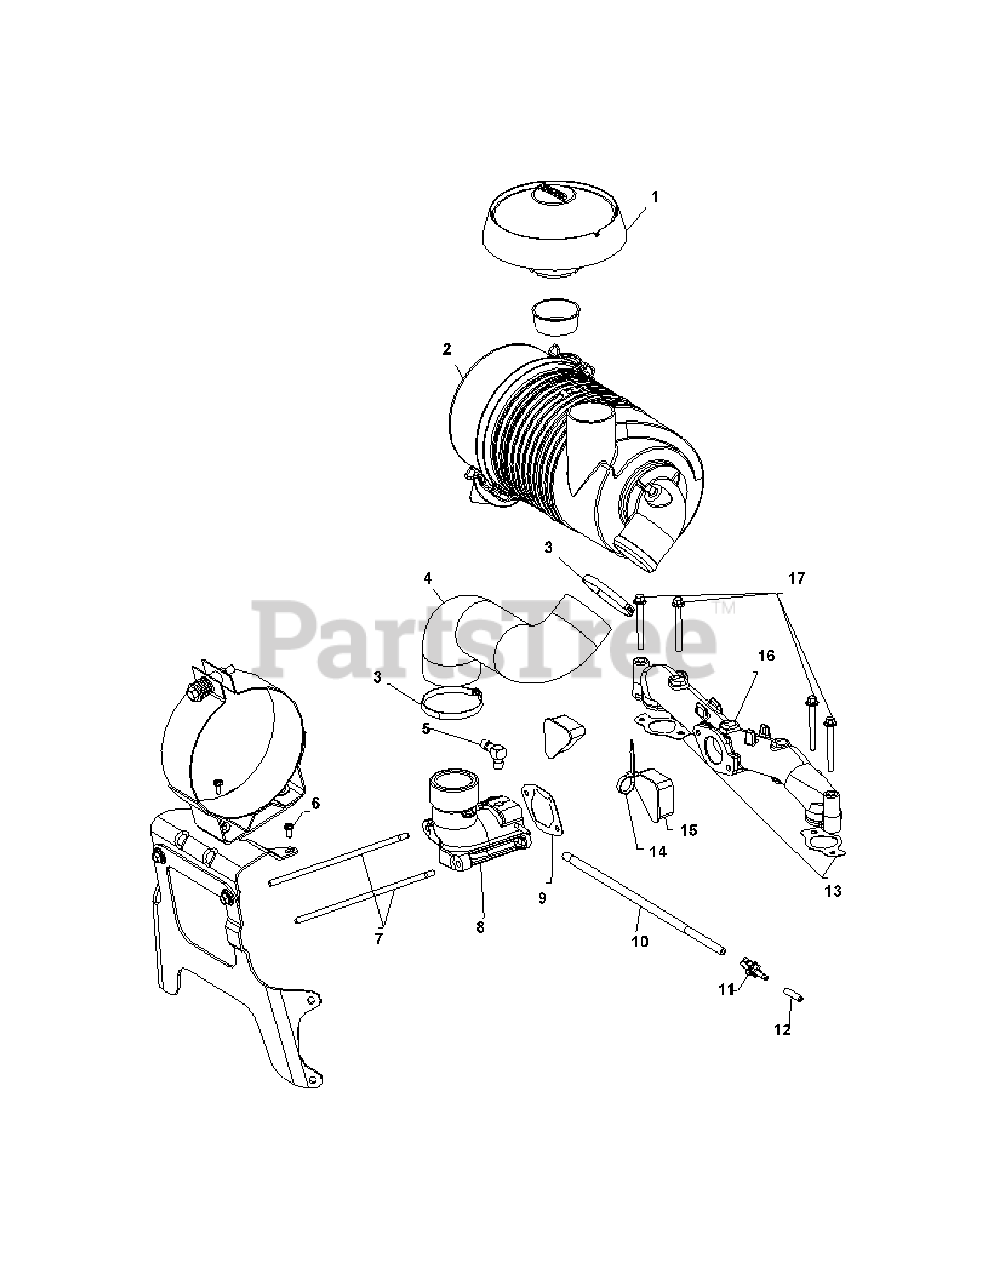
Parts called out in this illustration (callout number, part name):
3	Clamp, Hose (Round Zinc-Plated)
4	Hose, Air Cleaner
5	Connector, Hose
6	Screw, Wsh Hd Tap #8-18X1/2''
7	Stud, M6X1.0X180
9	Gasket, Air Cleaner Base
10	Hose, Evaporative, 20''
11	Connector, Evaporative
13	Gasket, Intake Manifold
15	Cover, Blower Housing
16	Manifold, Intake
17	Screw, Flg M6X1.0X55
